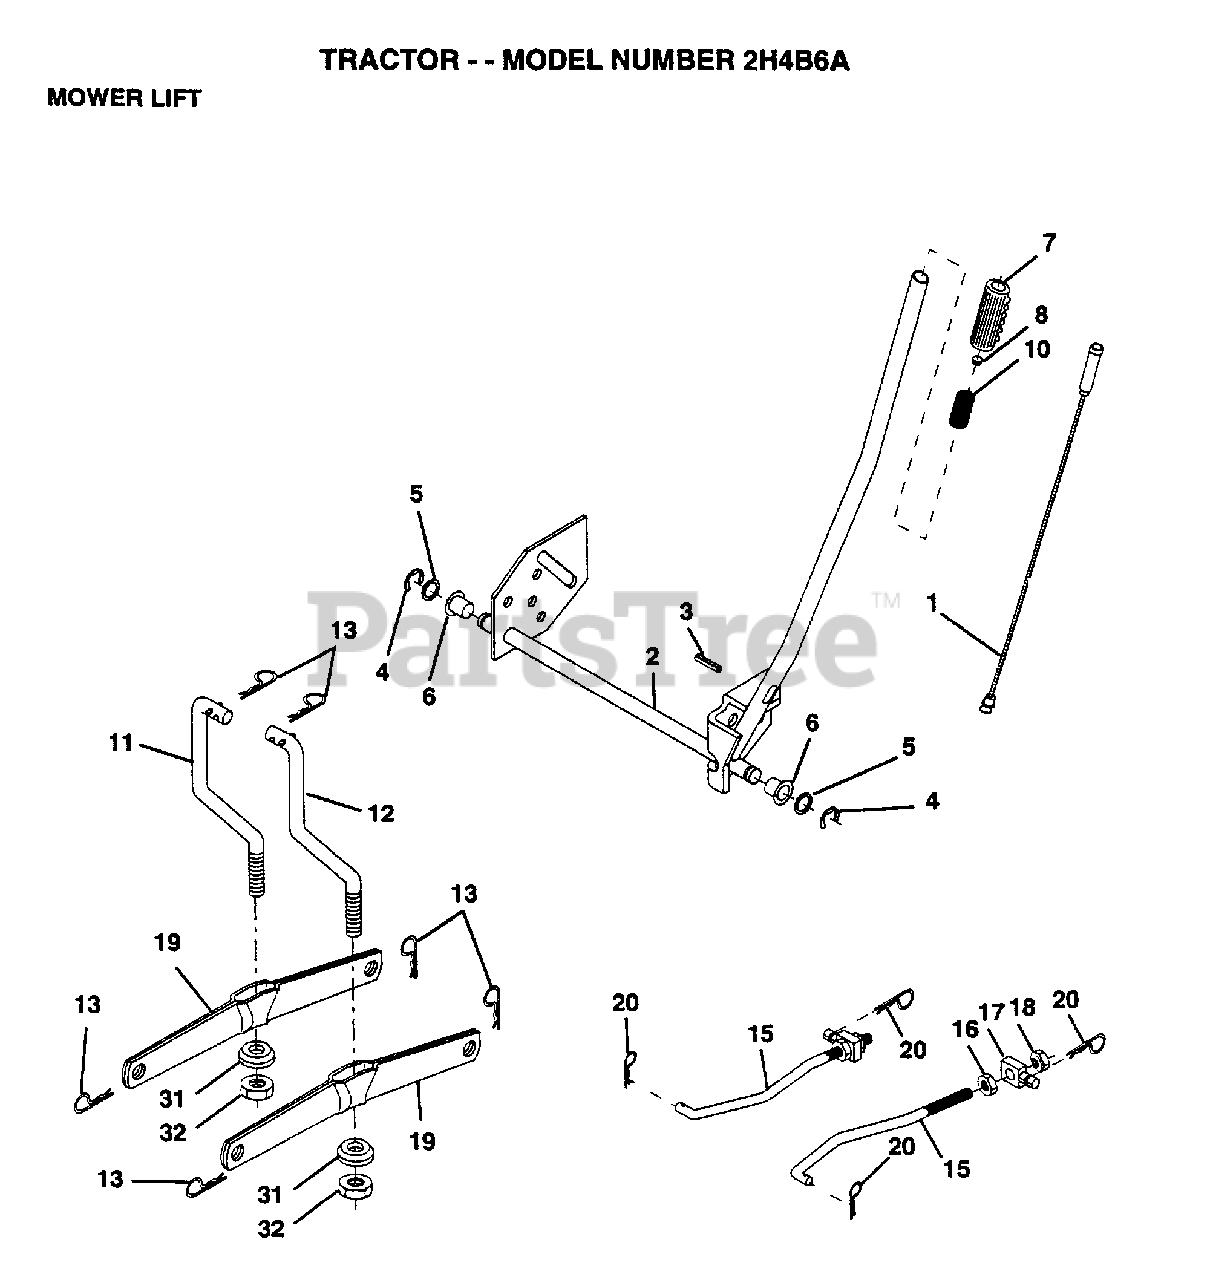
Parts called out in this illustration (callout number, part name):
1	WIRE ASM
3	PIN-GROOVE LT
5	WASHER
6	NYLON BEARING
7	GRIP
15	LINK.FRONT
16	NUT
17	TRUNION
18	NUT.LK.W/WSH.1/2.
19	ARM SUSP REAR
20	RETAINER.SPRING
31	BEARING PVT LH
32	NUT.CROWNLOCK.3/8
